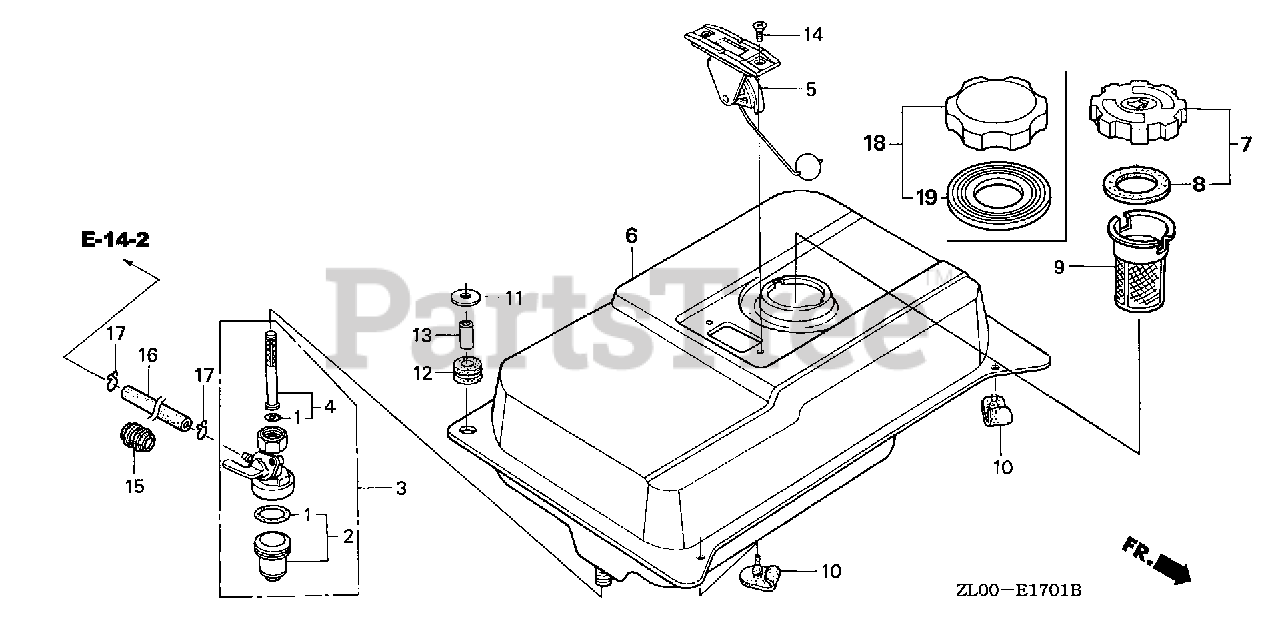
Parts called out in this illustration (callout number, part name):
1	GASKET SET, PETCOCK (CONTAINS 1 LARGE & 1 SMALL. USE AS NEEDED)
2	CUP, FUEL STRAINER
3	PETCOCK ASSY.
4	SCREEN SET
5	METER ASSY., FUEL
6	TANK, FUEL *R280* (POWER RED)
7	CAP, FUEL FILLER (BLACK)
8	GASKET, FUEL FILLER CAP (39X58X3)
9	FILTER, FUEL
10	RUBBER, TANK MOUNTING
11	WASHER, AIR DUCT
12	RUBBER, CONTROL BOX
13	COLLAR, CONTROL BOX
14	SCREW, FLAT (5X10)
